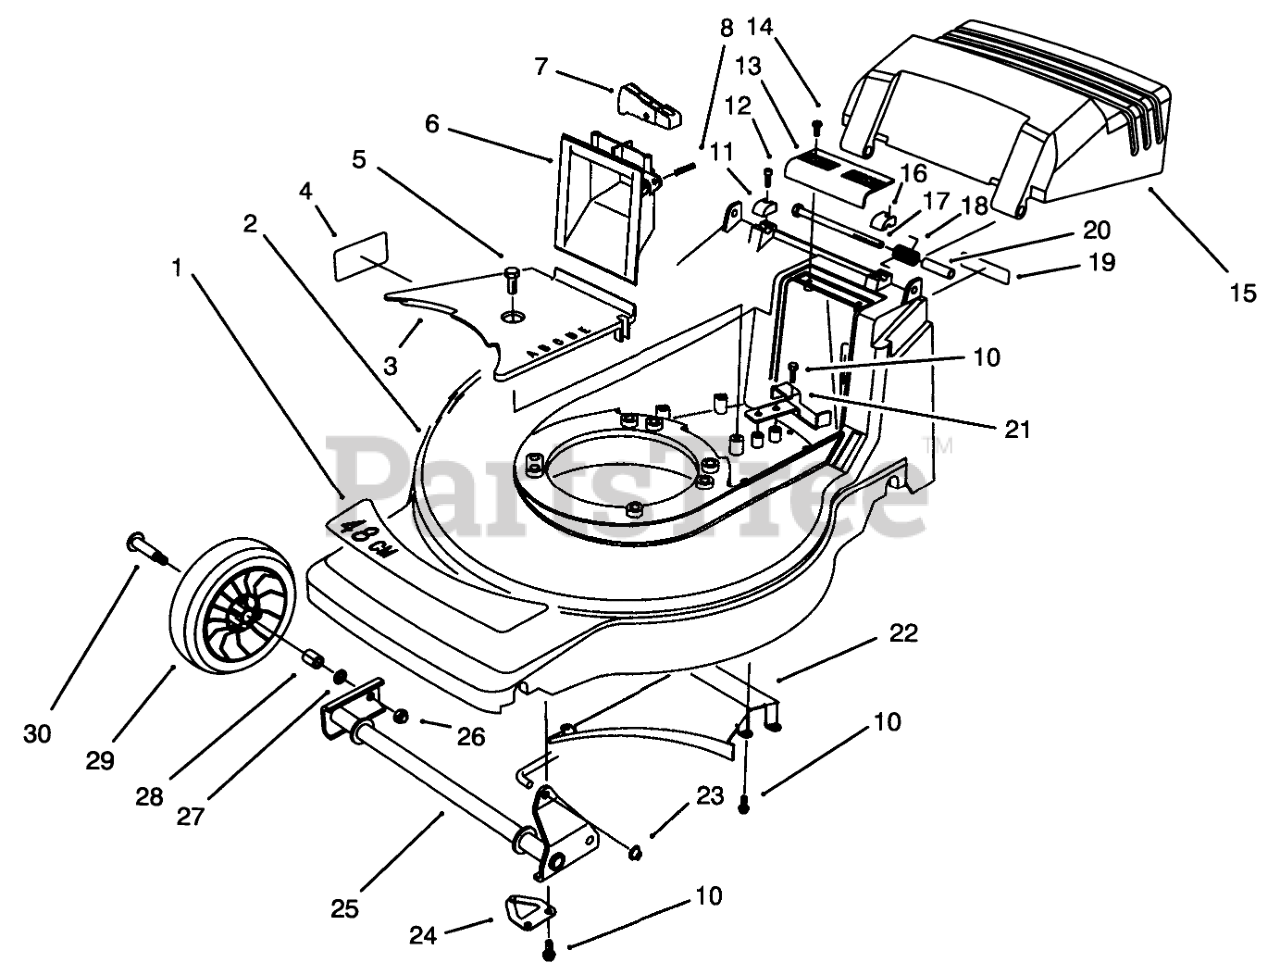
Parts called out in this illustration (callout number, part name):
1	DECAL - DECK 48 CM
2	Housing-48cm (Incl.Ref.#4)
3	BELT COVER
4	DECAL - DIN/DANGER
5	SCREW-HWHTF
6	GRIP - LOWER
7	TRIGGER - HOC
8	PIN-SPIRAL
10	SCREW-HWH
11	CAP-HINGE BOLT, RH
12	SCREW-HSH
13	GRIP-UPPER
14	SCREW-PPH, PLASTITE
15	Door Discharge
16	CAP-HINGE BOLT, LH
17	SCREW-HH
18	SPRING-DOOR
19	DECAL FRENCH REGUL.
20	SPACER-DOOR
21	REAR BELT GUIDE
22	Ramp-Discharge
23	NUT-PUSH
24	SHAFT RETAINER ASM
25	FRONT PIVOT WA
26	NUT-HEX
27	WASHER
28	BUSHING
29	Wheel & Tire Assembly (Incl.Ref.#28)
30	BOLT-WHEEL
